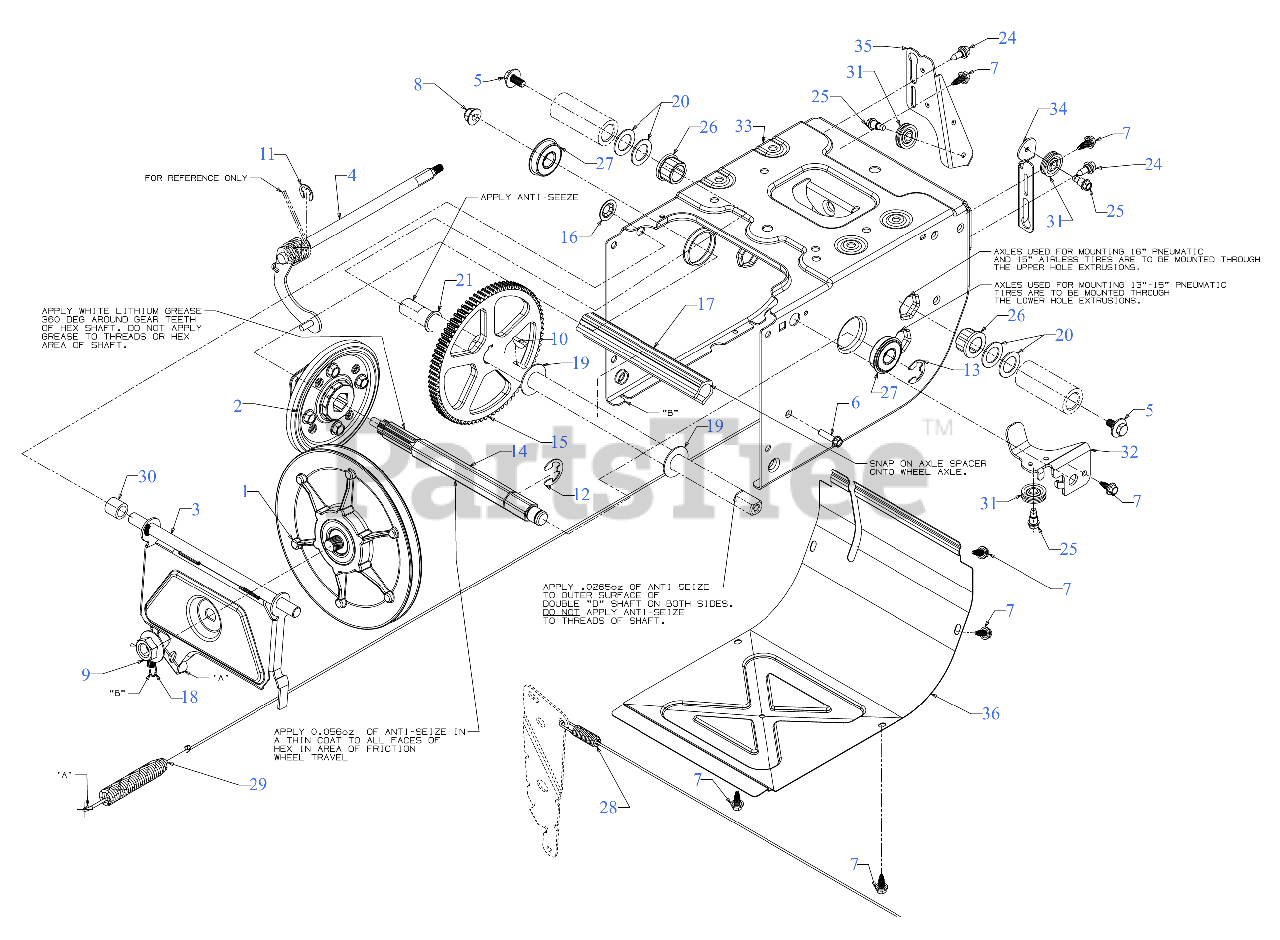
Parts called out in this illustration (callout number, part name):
1	FRICTION WHEEL DISC ASSEMBLY
2	FRICTION WHEEL ASSEMBLY
3	FRICTION WHEEL BRACKET (POWDER BLACK)
4	SHIFT ROD ASSEMBLY
5	SCREW 5/16-24 x .750 GR5
6	SCREW 1/4-20 x 1.00
7	SCREW 1/4-20X.625
9	FLANGE NUT 5/8-18
10	KEY-HI-PRO #9-3/16X3/4 DIA
11	E-RING FOR .500 SHAFT
12	RETAINING RING
13	E-RING
14	HEX SHAFT .8125 HEX 7 TOOTH
15	80-TOOTH GEAR
16	PUSH CAP
17	SPACER-AXLE 7.40"
18	EXTENSION SPRING
19	FLAT WASHER .760ID X1.49OD x .06
20	FLAT WASHER .793 ID X1.240X.06
21	FLAT WASHER .750X1.000X.060:HD
24	SHOULDER SCREW
25	SHOULDER SCREW
26	FLANGE BEARING
27	BALL BEARING W/RET
28	AUGER DRIVE CABLE 47.48"
29	WHEEL DRIVE CABLE 44.955"
30	SPACER-.513 ID x .703 OD x .69
31	CABLE GUIDE ROLLER
32	AUGER CABLE BRACKET
34	AUGER CABLE GUIDE BRACKET
35	GUIDE BRACKET
